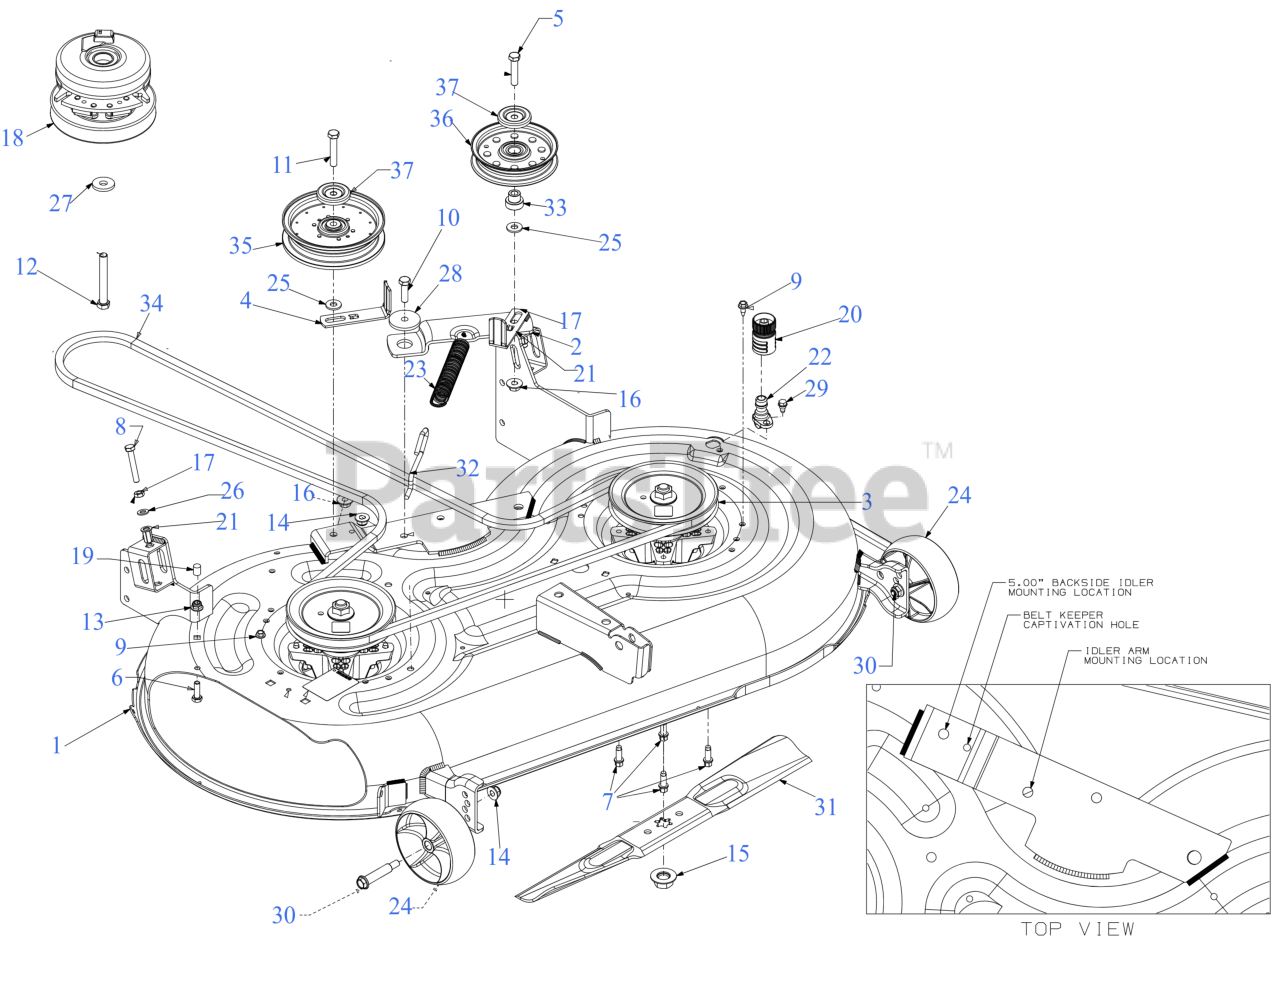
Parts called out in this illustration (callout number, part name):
1	42" DECK SHELL
2	IDLER PIVOT BRACKET
3	SPINDLE ASSEMBLY
5	HEX SCREW 3/8-16 x 1.75 GR5
6	SCREW 5/16-18 x 1.0 GR5
7	SCREW 5/16-18 x .875
8	SCREW-FULL THREAD 5/16-18 GR5
9	SCREW 1/4-20X.625
10	SCREW 3/8-16 x 1.25 GR5
11	SCREW 3/8-16 x 2.0 GR5
12	SCREW 7/16-20 x 3.25 GR5
13	FLANGE LOCK NUT 5/16-18
16	FLANGE LOCK NUT
18	ELECTRIC PTO CLUTCH
20	WATER NOZZLE ADAPTER
21	NUT RIVET 5/16-18
22	DECK WASH NOZZLE
23	EXTENSION SPRING .94 x 6.75 RZT
24	DECK WHEEL (5.0 DIA x 1.875)
25	FLAT WASHER .385X.870X.090
26	FLAT WASHER
27	FLAT WASHER .445 x 1.248 x .170
28	SHOULDER SPACER
29	SHOULDER SCREW 1/4-20 x .50
30	SHOULDER BOLT (.50 X 2.0 x 3/8 -16)
31	21.23" BLADE (2N1)
32	DECK SPRING HOOK
33	SHOULDER SPACER
34	V-BELT A SEC x 117.0
35	FLAT IDLER PULLEY
36	IDLER PULLEY 4.25 DIA
37	IDLER PULLEY CAP
